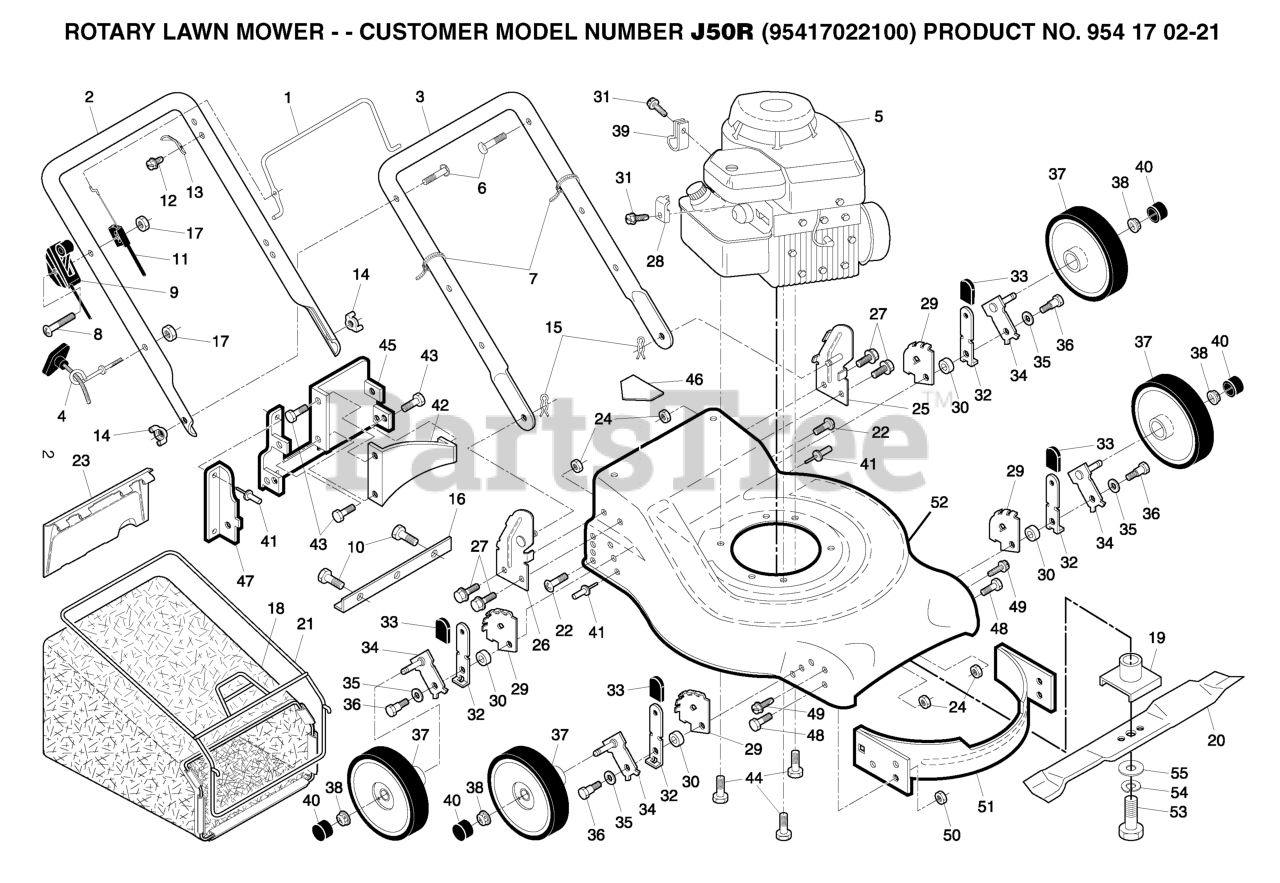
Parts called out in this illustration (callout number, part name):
1	BAIL.CONT.D.STRAIGHT.PUSH.BLK
3	HANDLE
4	ROPE, GUIDE
6	BOLT, HANDLE 5/16-18X1.75
7	TIE GUIDE
8	SCREW.PAN.HEAD
11	CABLE.MZR.51.RT.SP./PU.
13	BRACKET UPSTOP
14	KNOB, DEFLECTOR
15	HAIRPIN COTTER
16	REPL BY 532 14 61-43
17	NUT
19	BLADE ADAPTOR
20	BLADE.20.MULCH.(50DK,6020MD)
21	CATCHER.FRAME.WALK
22	HINGE SCREW
23	REAR DOOR ASSEMBLY KIT
24	LOCKNUT PM
25	HANDLE BRACKET ASSEMBLY - LEFT
26	HANDLE BRACKET ASSEMBLY-RIGHT
27	SELF-TAPPING SCREW 5/16-18X3/4
28	CABLE CLAMP(ENGINE)
29	WHEEL ADJUST BRACKET
30	RP SPACER HT ADJ
31	SCREW.HEX.HEAD.WASHER.10-16
32	SELECTOR SPRING
34	AXLE, REAR
35	WASHER.BELLEVILLE (3 2 LB)
36	BOLT
37	WHEEL
38	HEX FLANGE LOCKNT
39	GUIDE CLIP PM
41	RIVET BLIND
44	BOLT 3/8-16X1-1/8
46	DECAL.INTERNATIONL.CUTFINGER
47	SIDE BAFFLE
48	SCREW 1/4X20
50	LOCK NUT
53	SCREW, HEX HD 3/8-24 X 1-3/8
54	LOCKWASHER
55	WASHER,HARDEN
